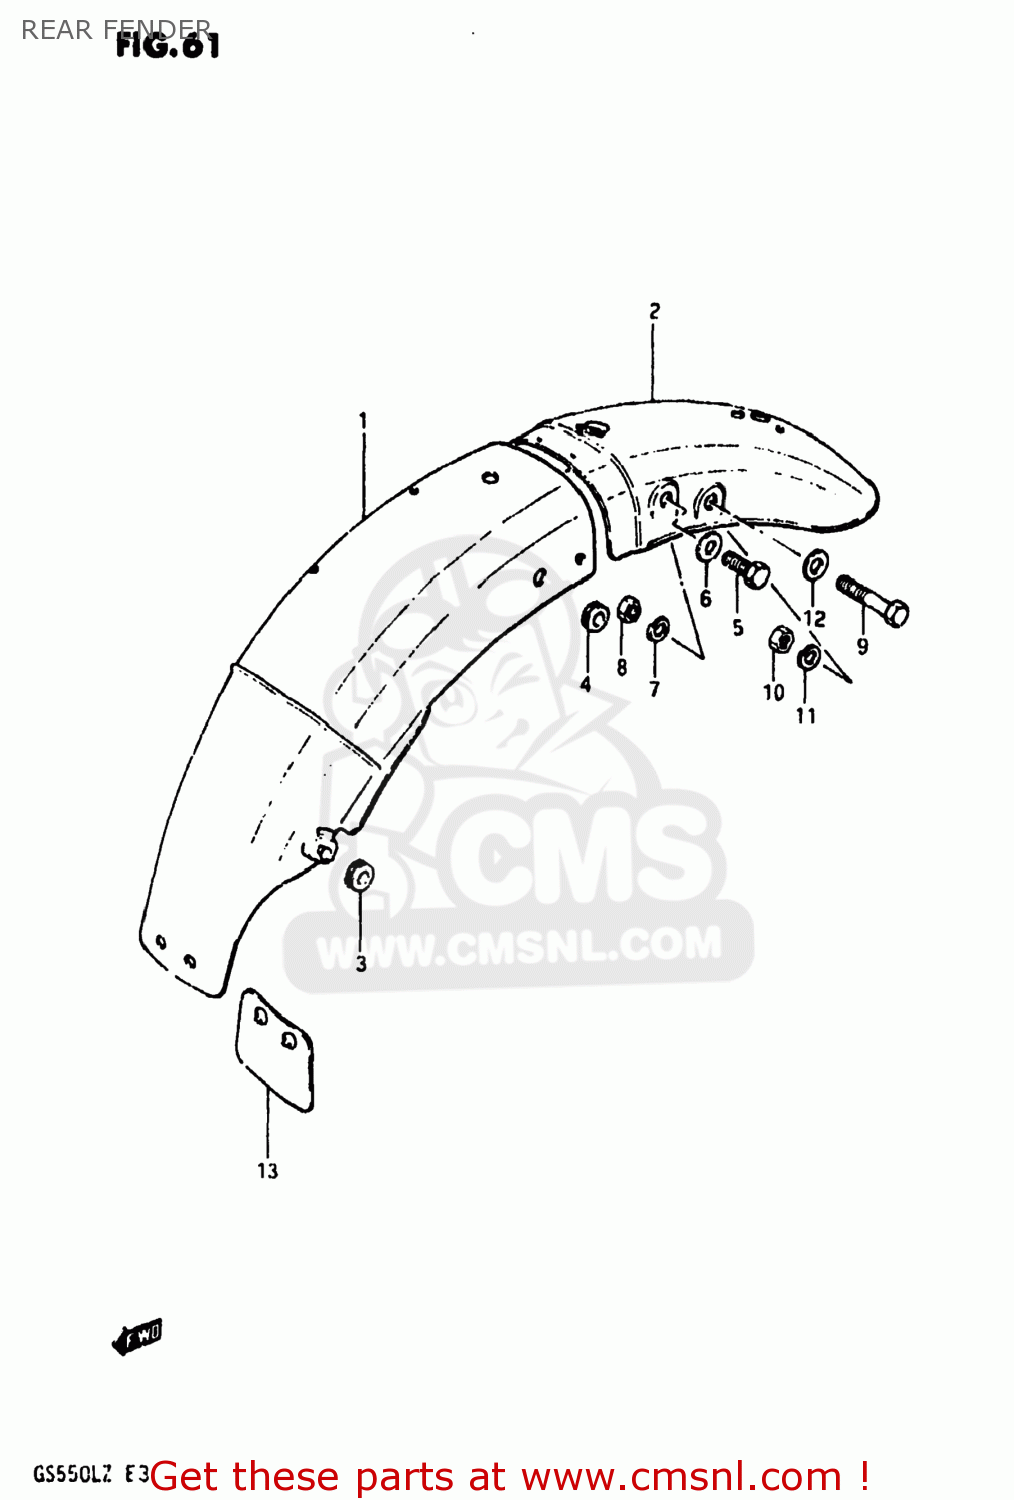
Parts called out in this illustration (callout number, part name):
1	FENDER,REAR
2	FENDER,REAR
3	CUSHION
4	CUSHION
5	BOLT
6	WASHER
7	LOCK WASHER
8	NUT
9	BOLT
10	NUT 8MM
11	LOCK WASHER
12	WASHER
13	GUIDE,RR FENDER MUD
